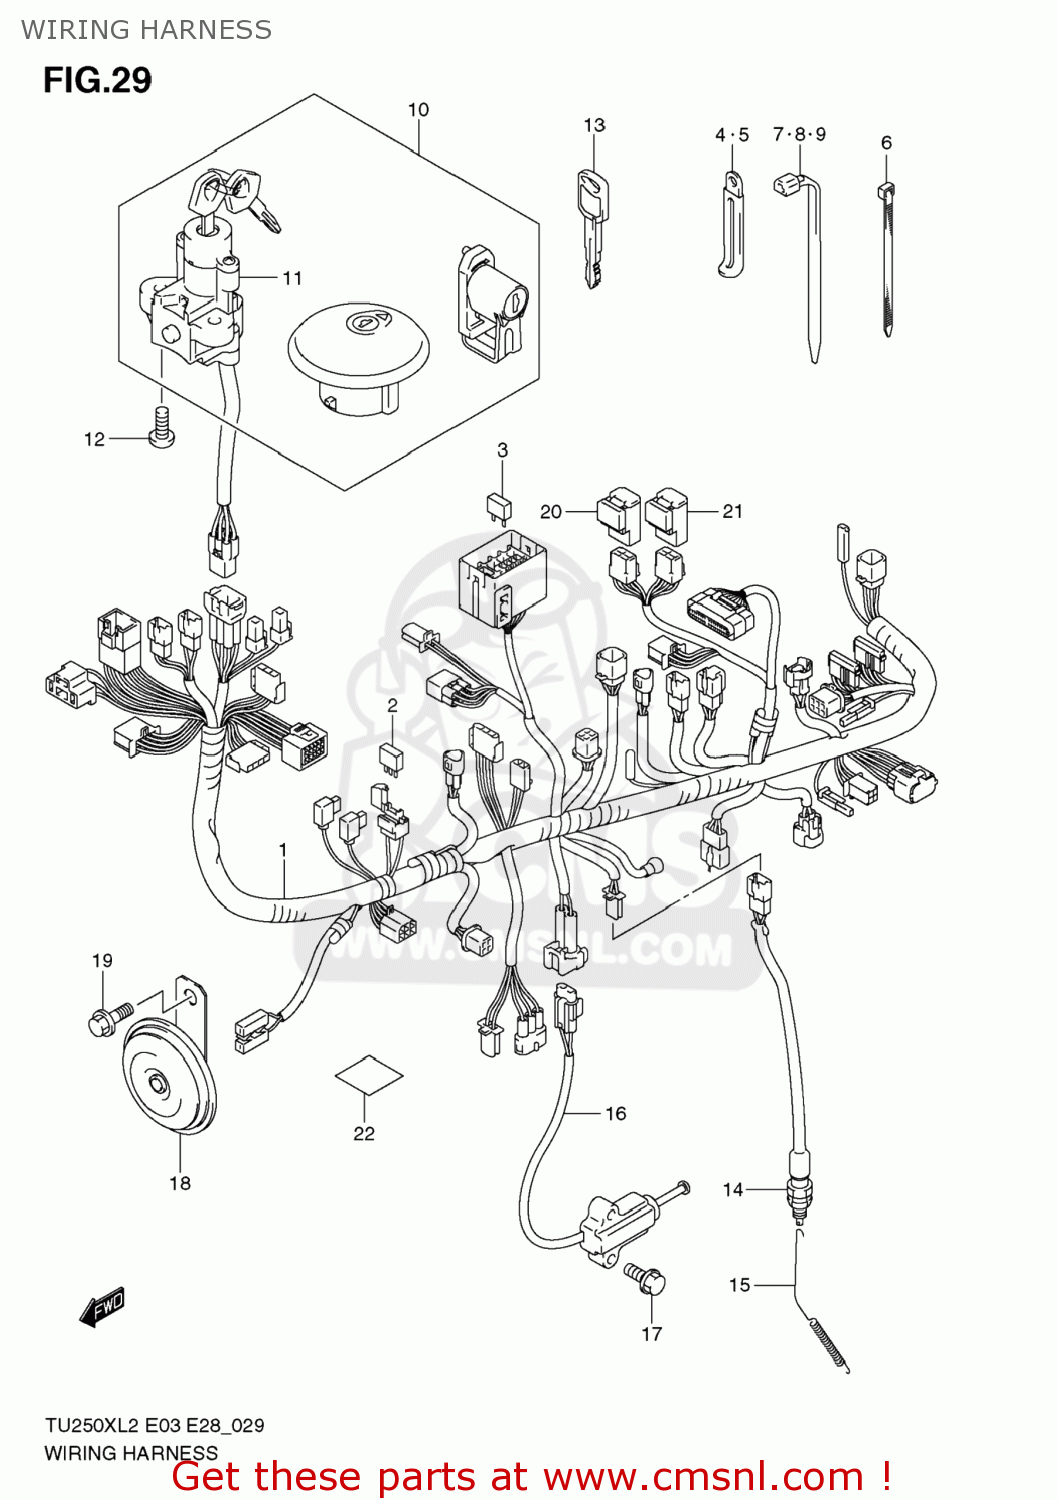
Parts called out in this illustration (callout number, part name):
1	HARNESS,WIRING
2	DIODE(STANLEY DE8804)
3	FUSE(10A)
4	CLAMP(L:80)
5	CLAMP(L:80)
6	CLAMP(L:95)
7	CLAMP(L:95)
8	CLAMP(L:125)
9	CLAMP(L:190)
10	LOCK SET
11	LOCK ASSY,STEERING
12	BOLT(8X20)
13	KEY,BLANK
14	SWITCH ASSY,STOP LAMP
15	SPRING
16	SWITCH ASSY,SIDE STAND
17	BOLT
18	HORN ASSY
19	BOLT
20	RELAY ASSY
21	RELAY ASSY
22	PROTECTOR,WIRING HARNESS
